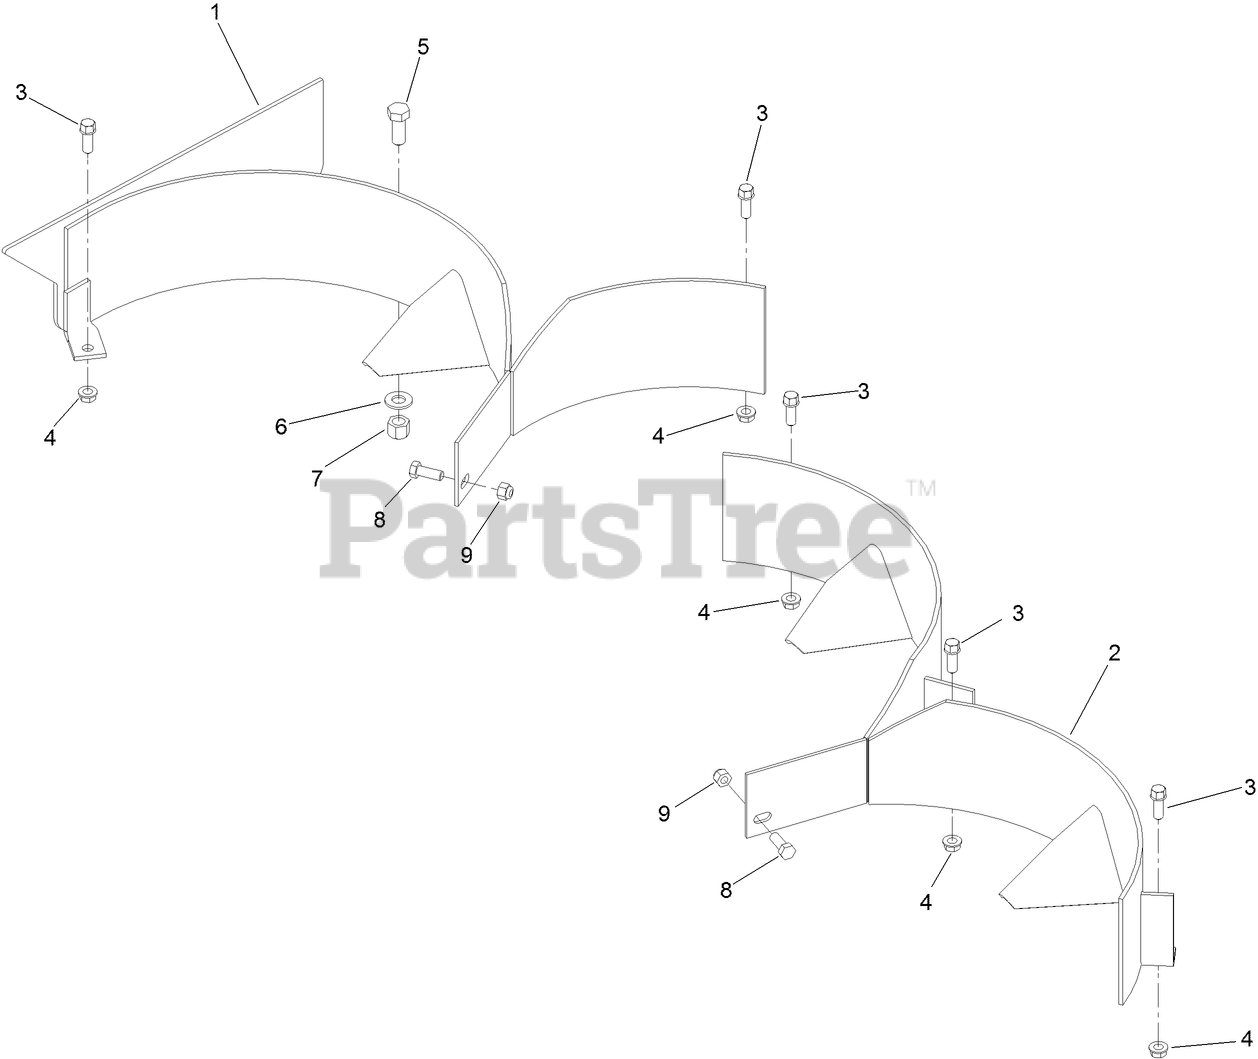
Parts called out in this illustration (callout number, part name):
1	BAFFLE-RH
2	BAFFLE-LH
4	NUT-HHF, WHIZ
5	SCREW-HH
6	WASHER-FLAT
7	NUT-LOCK, NI
8	SCREW-HH
9	NUT-LOCK, NI
